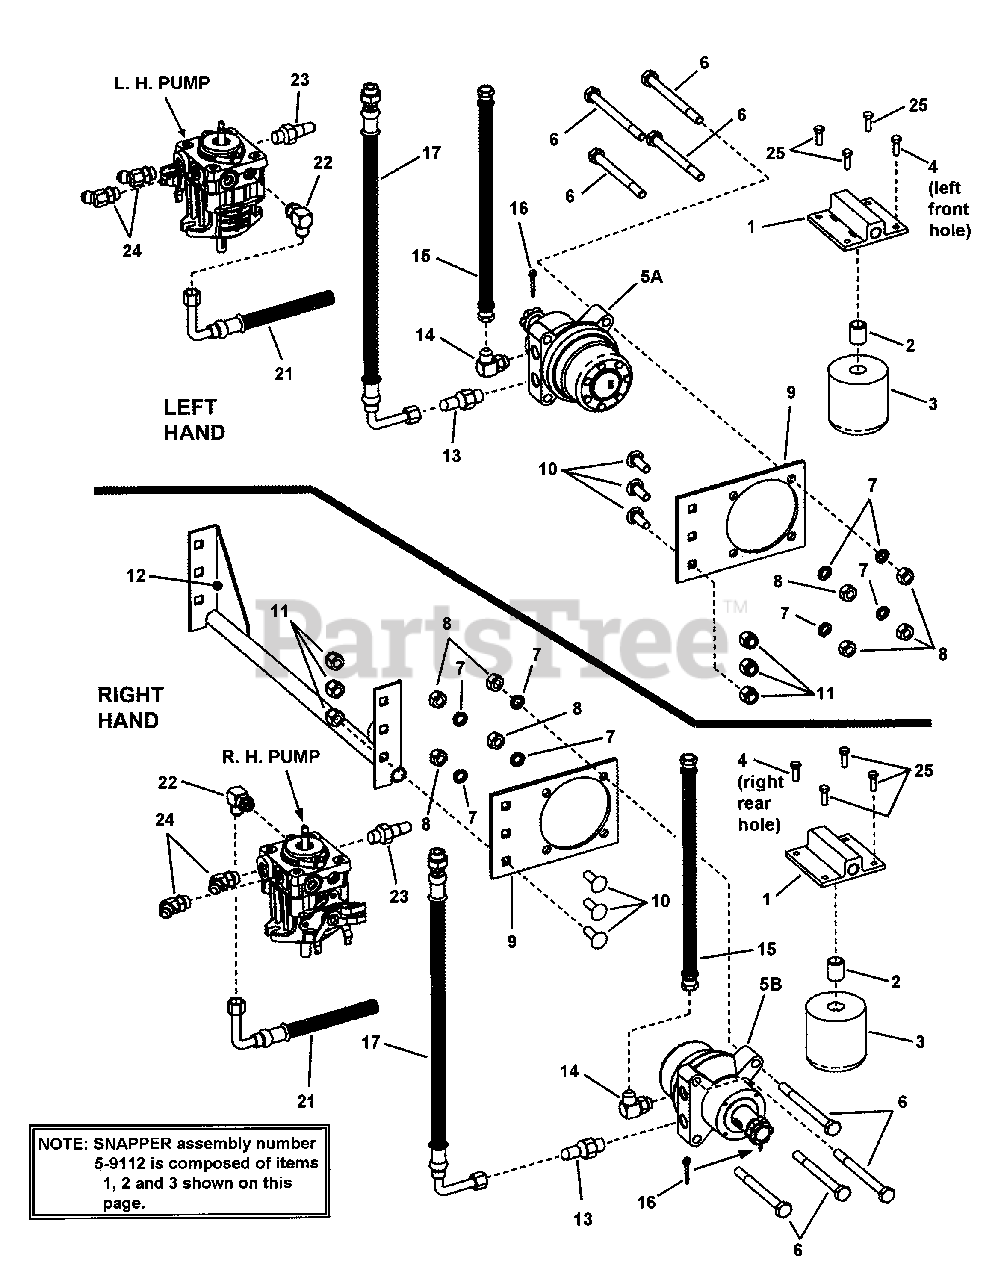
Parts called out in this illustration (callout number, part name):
1	MOUNT, Oil Filter
2	FITTING, Straight 1-12 UNF Thread
3	FILTER, Oil
4	SCREW, 3/8-16 x 3/4" Hex Washer Self-Tap
5A	MOTOR, Hydraulic, Left Hand
5B	MOTOR, Hydraulic, Right Hand
6	BOLT, 1/2-13 x 6" Hex Head Cap GR5
7	WASHER, 1/2" Split Lock
8	NUT, 1/2-13 HEX
9	PLATE, Mounting
10	BOLT, 1/2-13 x 1-1/2" Square Neck Carriage GR5
11	NUT, 1/2-13 Hex Nyloc
12	WELDMENT, Rear Crossbrace
13	CONNECTOR, Straight Hydraulic (Parker # 8-10 F5OLO-S)
14	CONNECTOR, 90 Degree Hydraulic (Parker # 8-10 C5OLO-S)
15	HOSE, 13-3/4" Hydraulic (Parker # F436BKJCJC080808-13-75)
16	PIN, 9/64 x 1-1/2" Cotter
17	HOSE, 17-1/2" Hydraulic (Parker # F436BKJCJ5080808-17.5)
21	HOSE, 6-1/2" (Parker # R836BKJ9NR080008-6.5
22	CONNECTOR, 90 Degree Hydraulic (Parker # 8-6 C5OLO-S
23	CONNECTOR, Straight Hydraulic (Parker # 8-6 F5OLO-S)
24	CONNECTOR, 45 Degree Hydraulic (Parker # V5OLO-S)
25	SCREW, 5/16-18 x 3/4" Hex Washer Self-Tap
